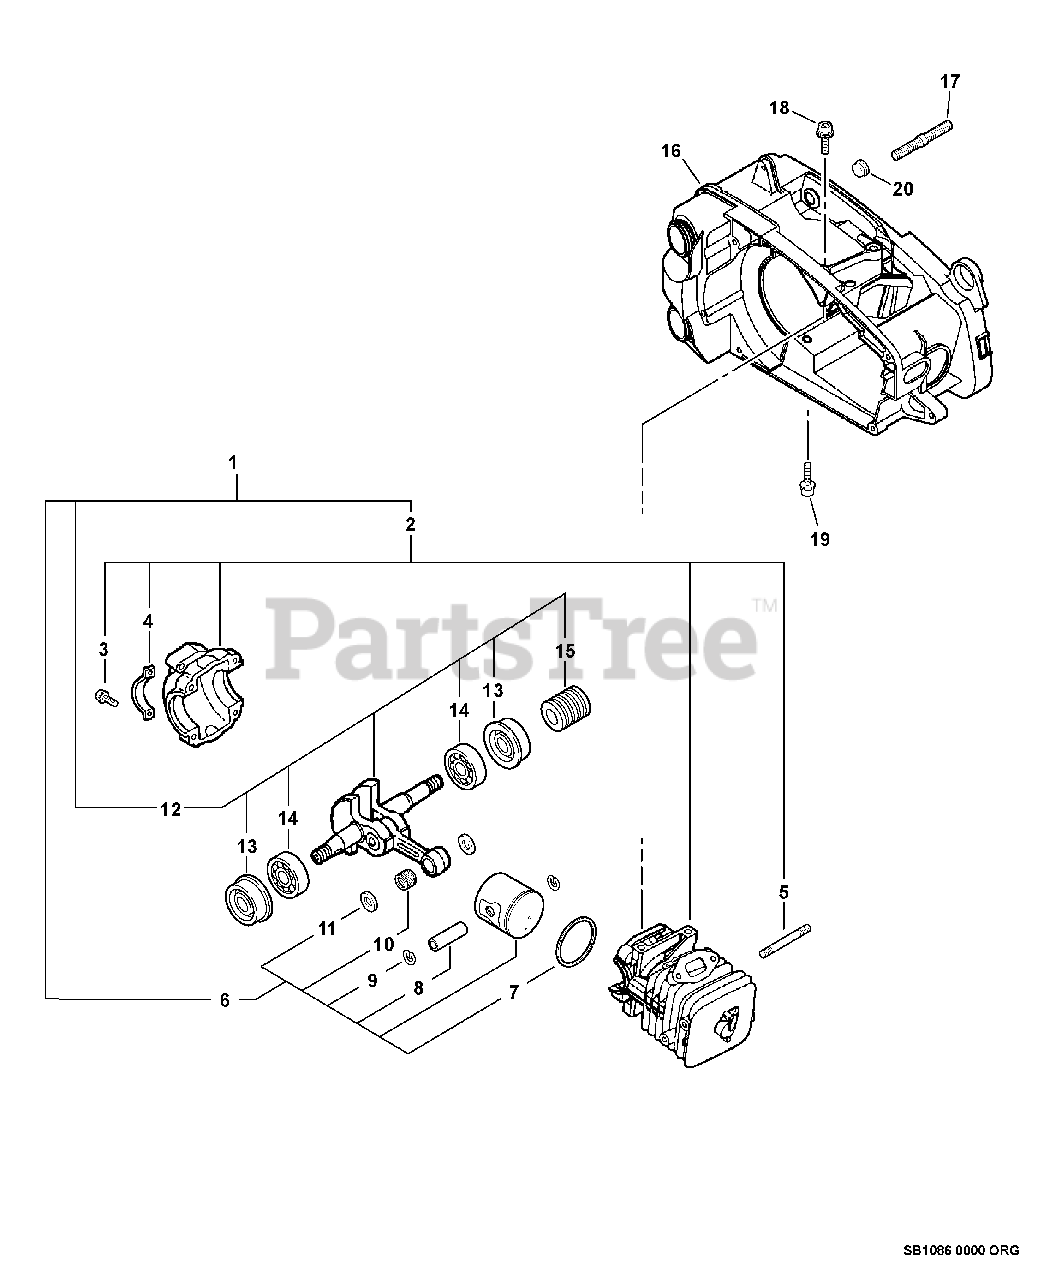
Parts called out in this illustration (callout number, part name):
1	SHORT BLOCK
2	CRANKCASE KIT
3	SCREW 5×25
4	BRACKET, CRANKCASE
5	BOLT, STUD
6	PISTON KIT
7	RING, PISTON
8	PIN, PISTON
9	RING, SNAP
10	BEARING, NEEDLE 8
11	WASHER, THRUST
12	CRANKSHAFT ASSY
13	SEAL, OIL 12
14	BEARING, BALL - 6201 C3
15	GEAR, WORM
16	COVER ASSY, ENGINE - ORANGE
17	BOLT, STUD 6
18	BOLT 5×20
19	BOLT 5×30
